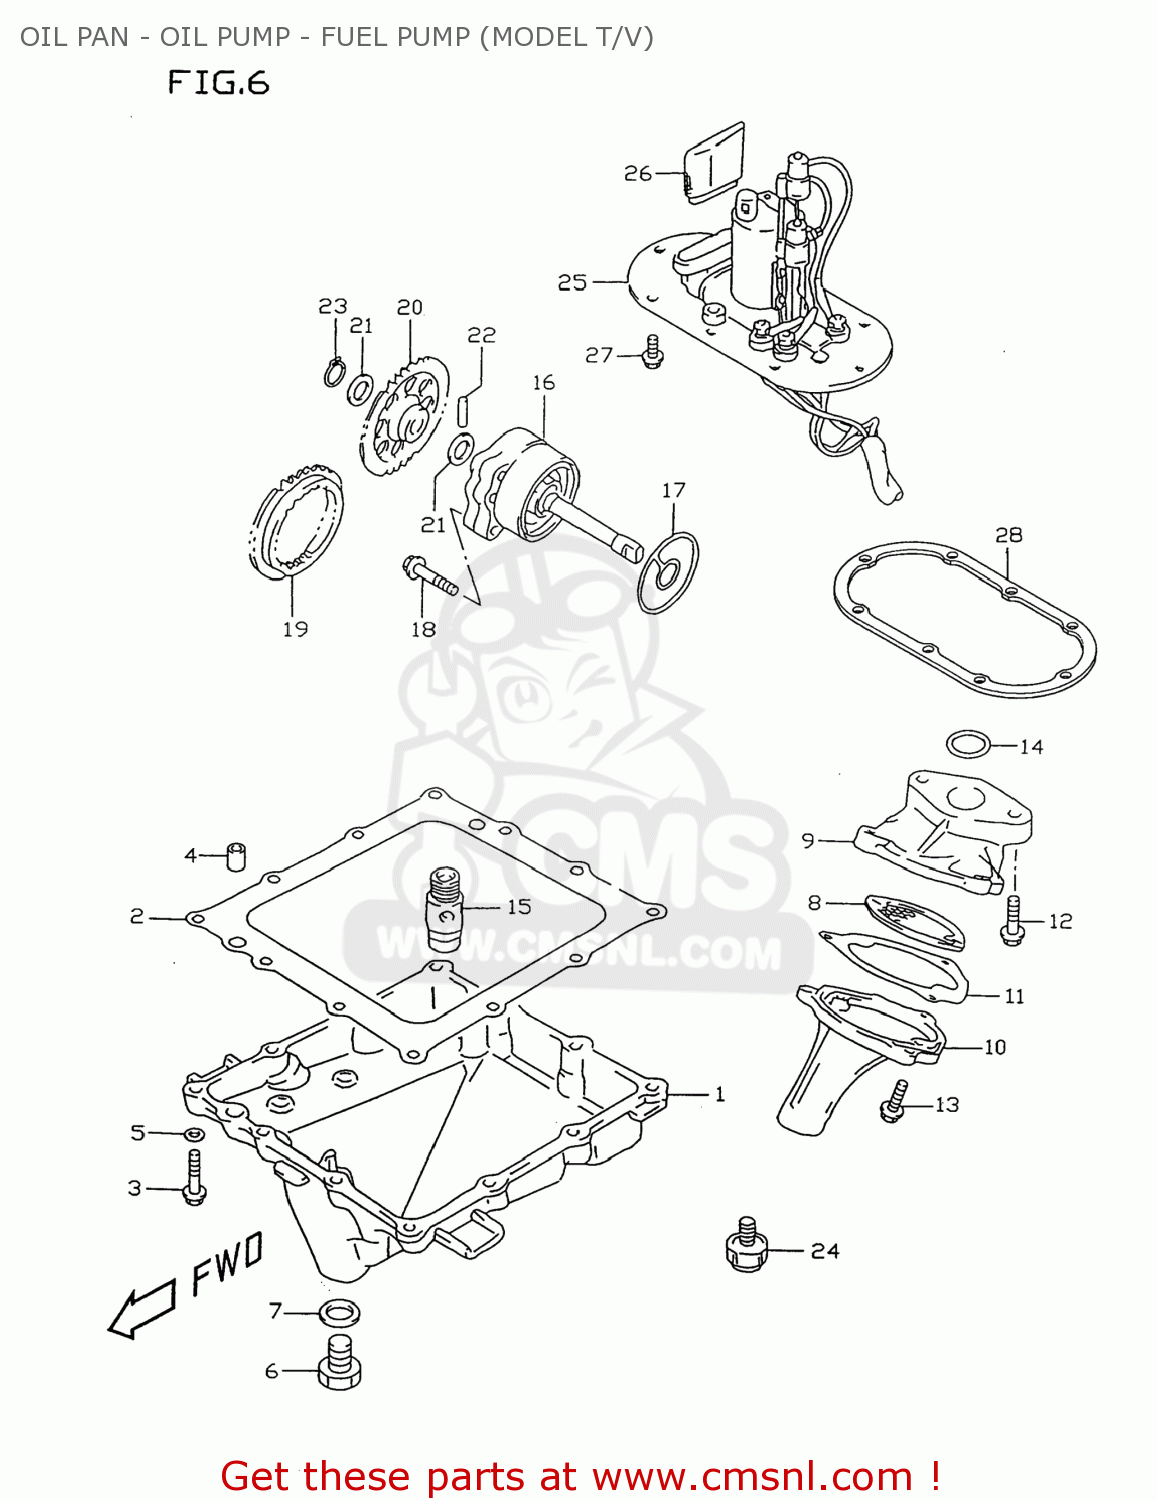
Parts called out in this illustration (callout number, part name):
1	PAN,OIL
2	GASKET,OIL PAN (NAS)
3	BOLT
4	PIN
5	GASKET(5.8X11X1.2) (NAS)
6	PLUG
7	GASKET(13.8X18.8X4.8) (NAS)
8	STRAINER,ENGINE OIL
9	PROTECTOR,OIL STRAINER
10	COVER,OIL STRAINER
11	GASKET,OIL STRAINER
12	BOLT
13	BOLT
14	O RING(D:2.62,ID:20.3)
15	VALVE ASSY,OIL RELIEF
16	PUMP ASSY,ENGINE OIL
17	O RING,OIL PUMP
18	BOLT
19	GEAR,OIL PUMP DRIVE (NT
20	GEAR,OIL PUMP DRIVEN(NT:37)
21	SHIM
22	PIN(5X18)
23	CIRCLIP,12 MM
24	SWITCH ASSEMBLY,OIL PRESSURE
25	PUMP ASSEMBLY,FUEL
26	STRAINER,FUEL PUMP
27	BOLT
